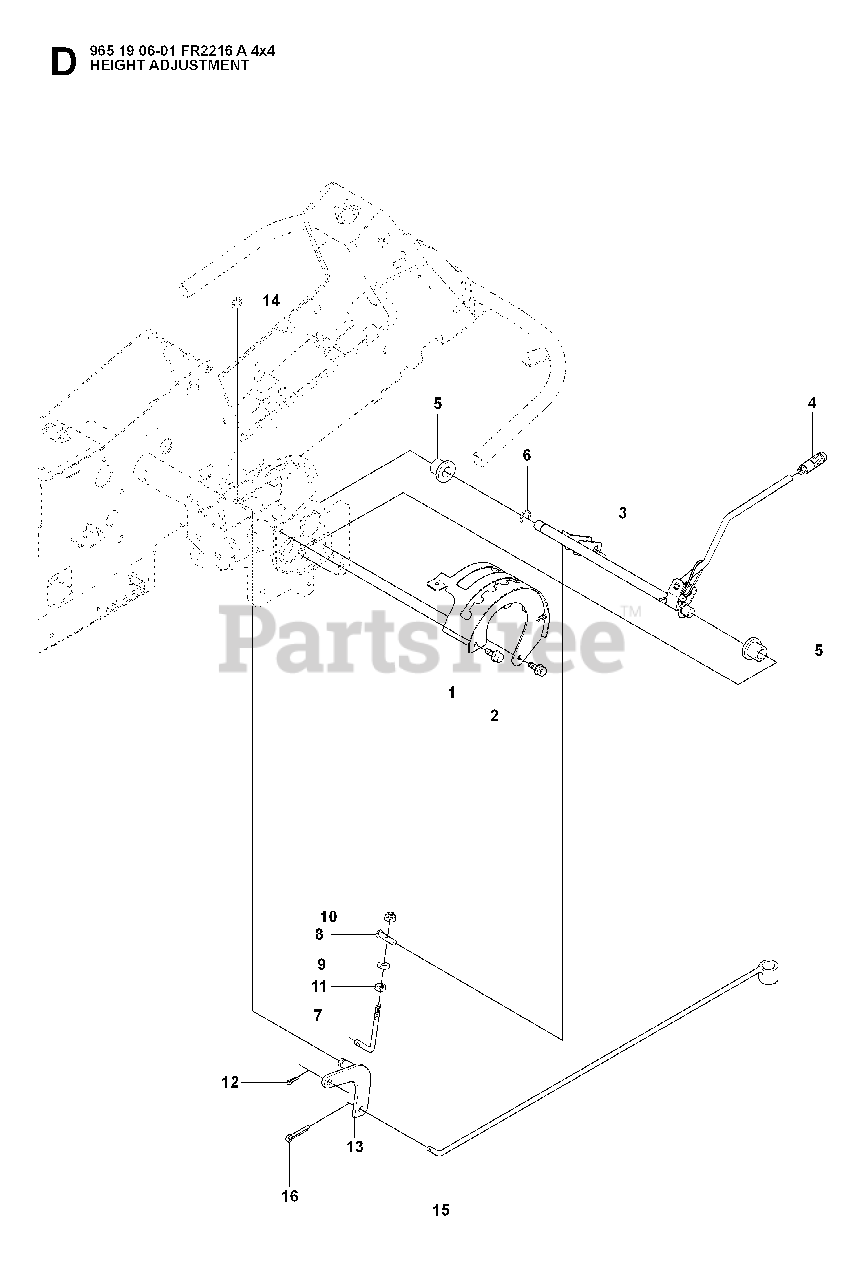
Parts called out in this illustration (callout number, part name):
4	GEAR STICK KNOB
5	BUSHING
9	WASHER
10	LOCKNUT M8
11	NUT
12	SPLIT PIN
14	RETAINING RING
15	CLUTCH ROD
16	SPLIT PIN
